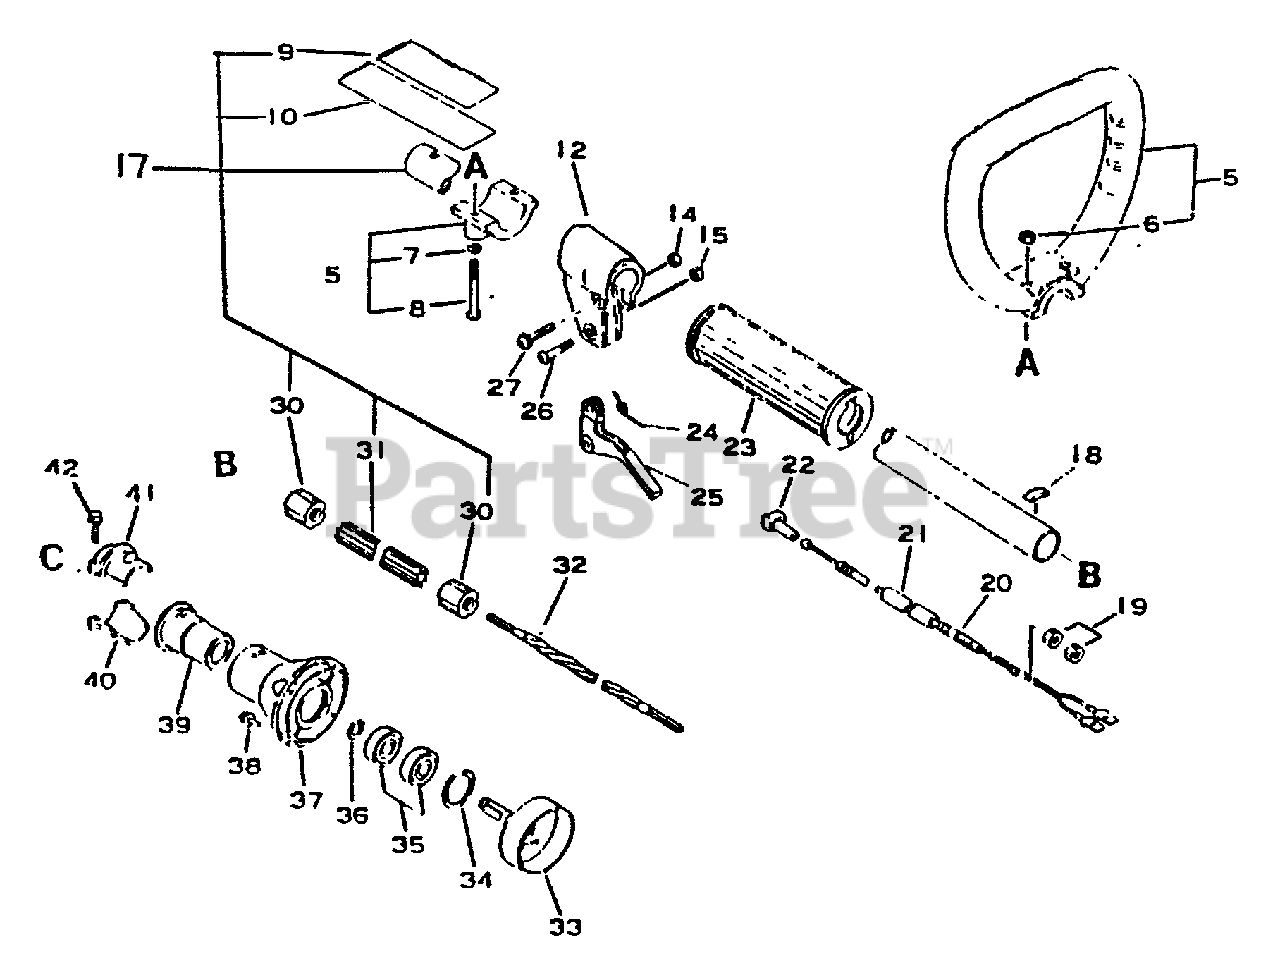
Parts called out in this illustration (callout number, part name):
5	Handle Ass'y, Loop
7	Washer 5
8	Screw 5-40
9	Label, Caution
10	Label, Caution
12	Bracket, Throttle
15	Locknut 5
17	Housing Ass'y D. Shaft
18	Label, Caution
19	Nut 6 03
20	Wire, Throttle
22	Holder, Thr. Wire
23	Grip, Handle
24	Spring. Thr. Return
25	Control, Throttle
27	Screw 5=30
30	Stopper
31	Liner, Flexible
32	Shaft, Flexible
33	Drum, Clutch
34	Circlip 28
35	Bearing, Ball 6001
36	Circlip 12
37	Case, Clutch
38	Screw 5=16
42	Bolt 5=25
